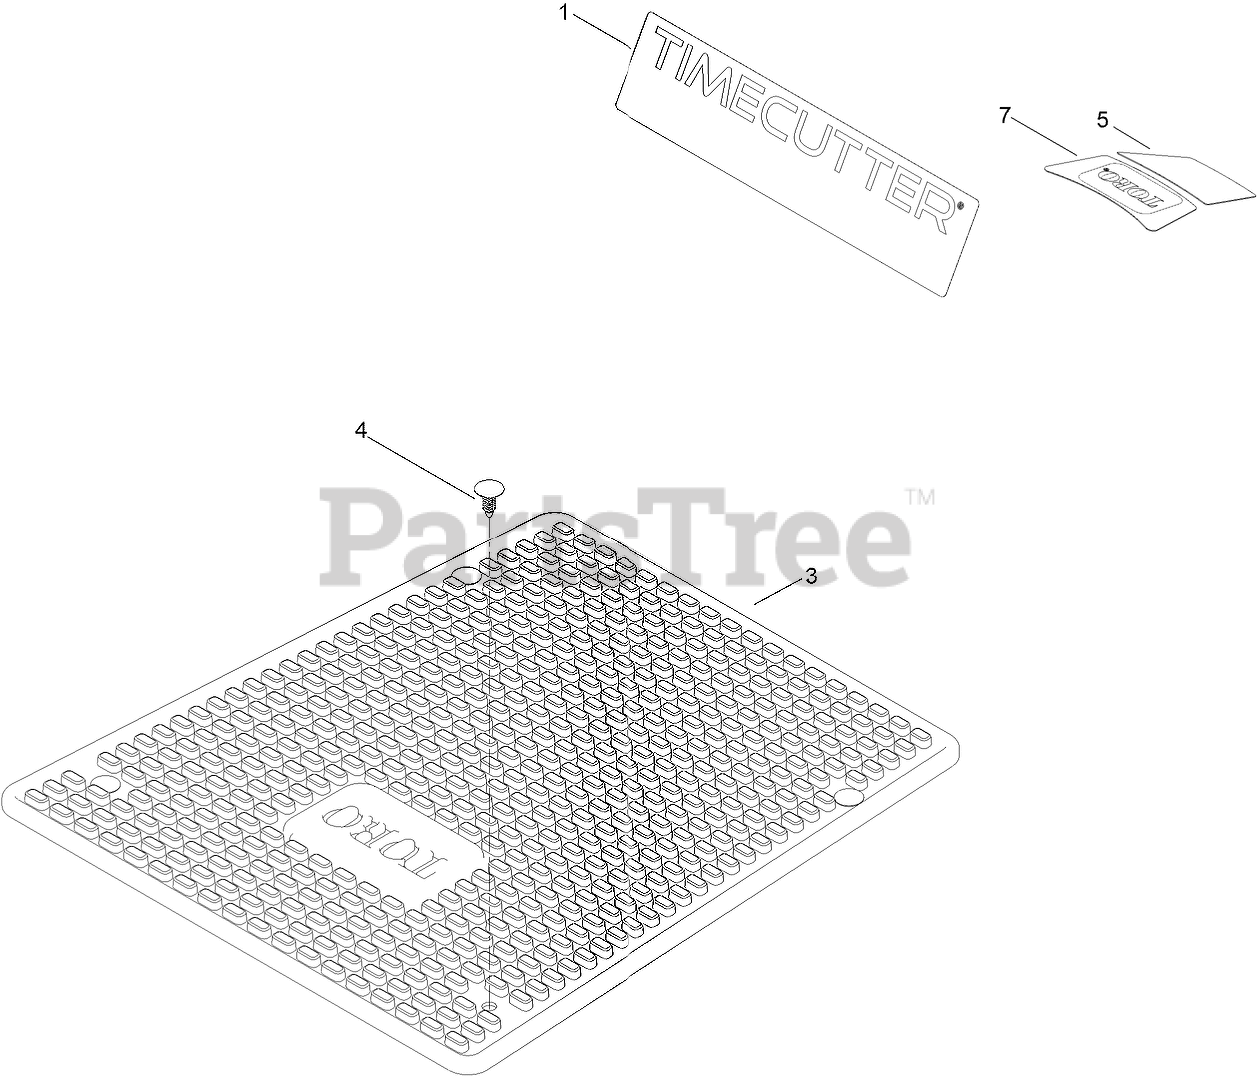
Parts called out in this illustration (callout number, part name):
1	DECAL-TIMECUTTER
3	MAT-FLOOR
4	PLUG-PLASTIC
5	DECAL-DISPLACEMENT, ENGINE
7	DECAL-ENGINE
